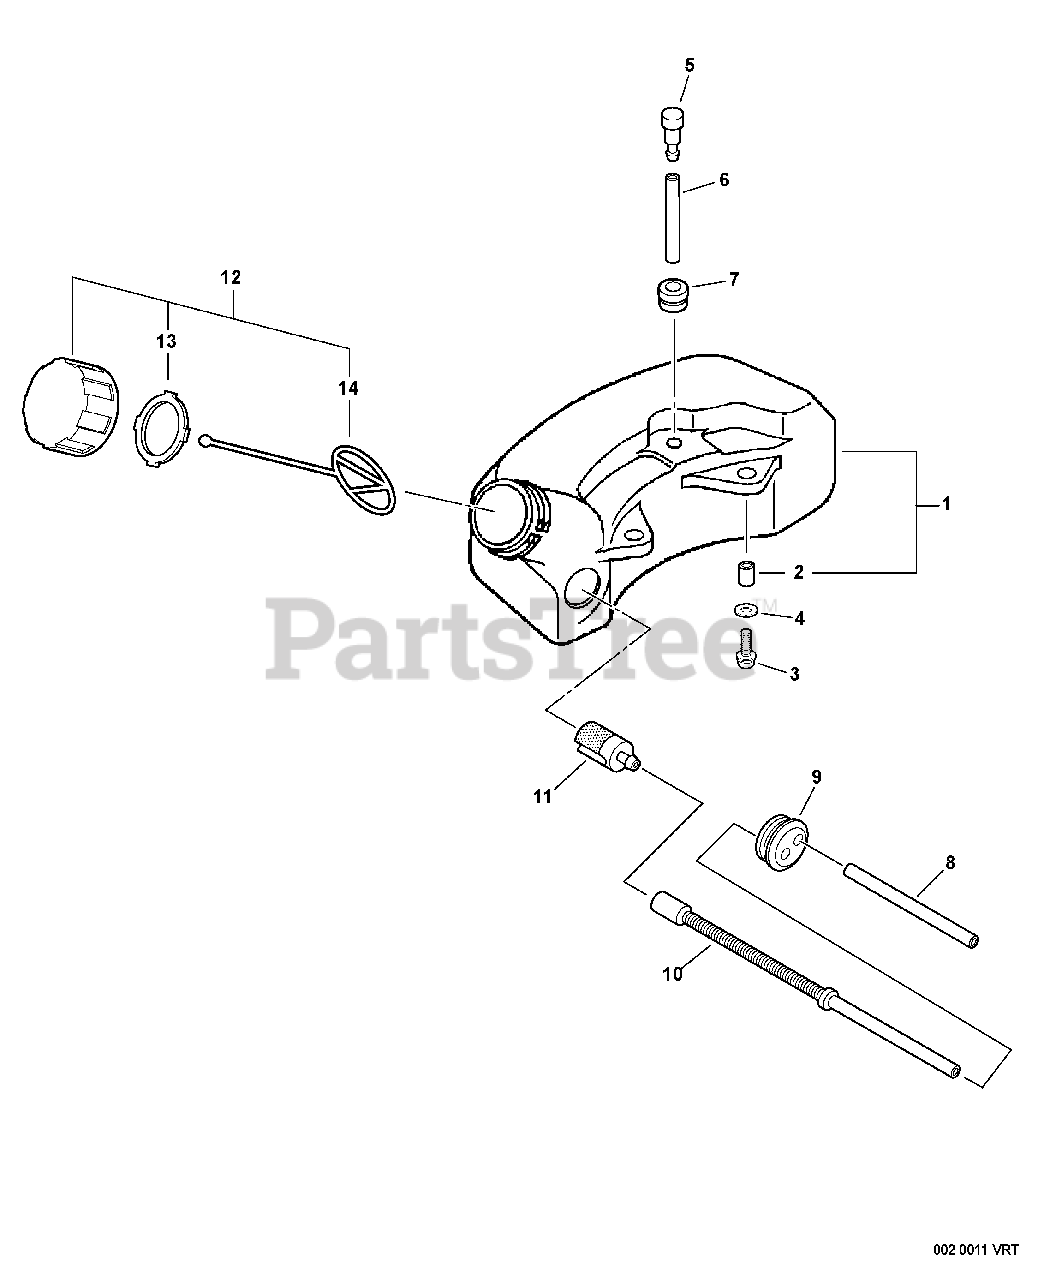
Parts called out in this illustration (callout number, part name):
1	TANK, FUEL
2	SPACER 6.2×7.8×6
3	BOLT 5×16
4	WASHER 5.5×12×0.8
5	VENT ASSY
6	PIPE, FUEL 3×6×35 BLACK
7	GROMMET
8	PIPE, FUEL RETURN 3×6×110
9	GROMMET, FUEL
10	PIPE, FUEL
11	FILTER, FUEL
12	CAP ASSY, FUEL
13	GASKET, FUEL CAP
14	CONNECTOR, CAP L= 100 MM
